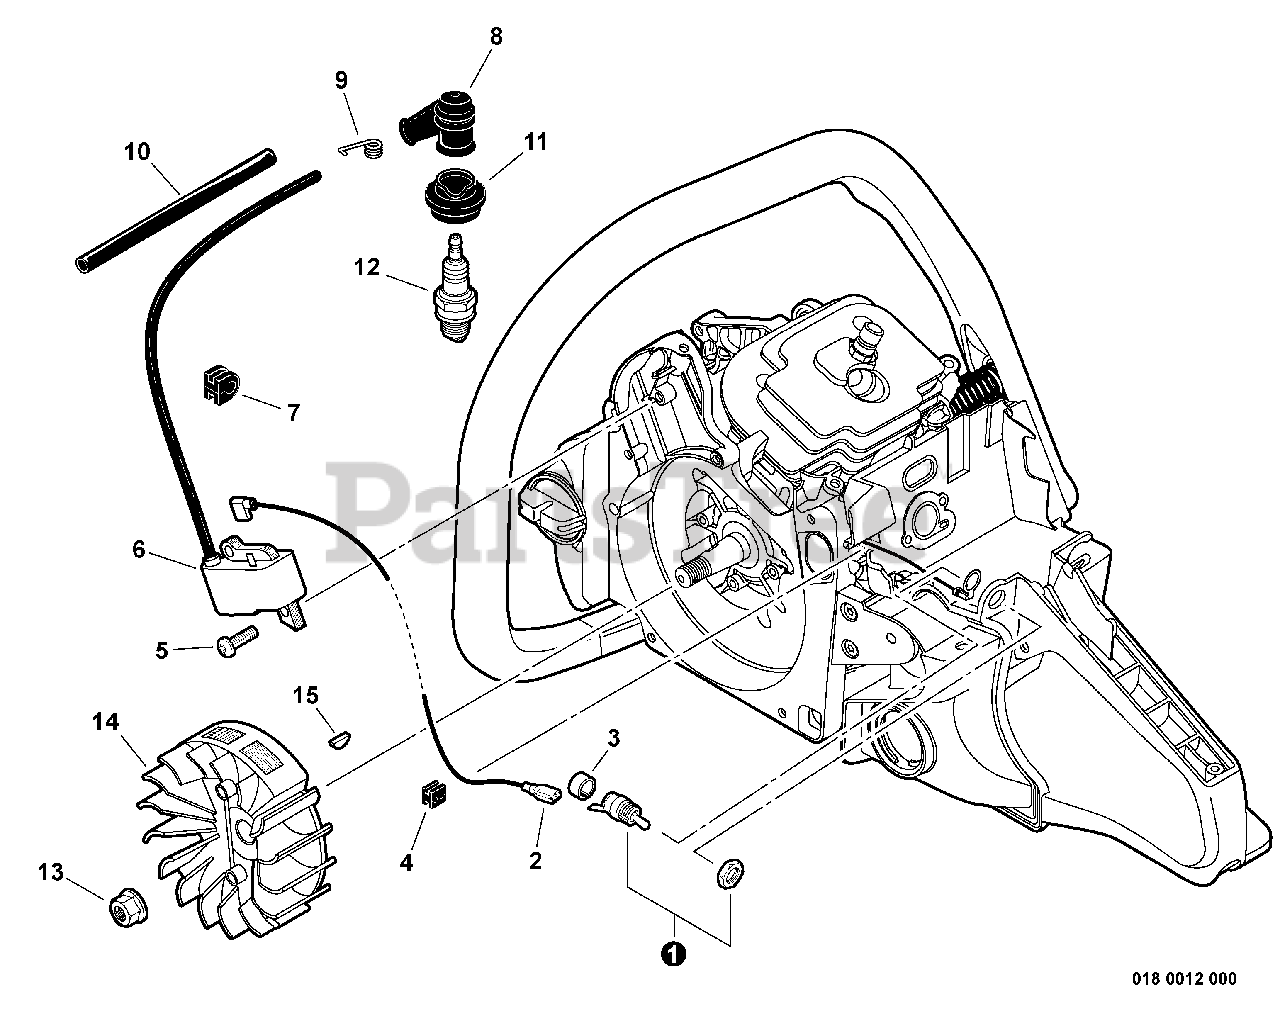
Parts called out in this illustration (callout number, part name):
1	SWITCH, ON-OFF
2	LEAD - IGNITION L= 280
3	CAP, SPARK PLUG
4	GROMMET, LEAD
5	BOLT, TORX 5×16
6	COIL, IGNITION
8	CAP, SPARK PLUG
9	TERMINAL, SPARK PLUG
10	TUBE, INSULATOR 6×7.2×65
11	SEAL, SPARK PLUG
12	SPARK PLUG - BPM8Y
12	SPARK PLUG - BPMR8Y
13	NUT, FLANGE M8
14	FLYWHEEL
15	KEY, WOODRUFF
